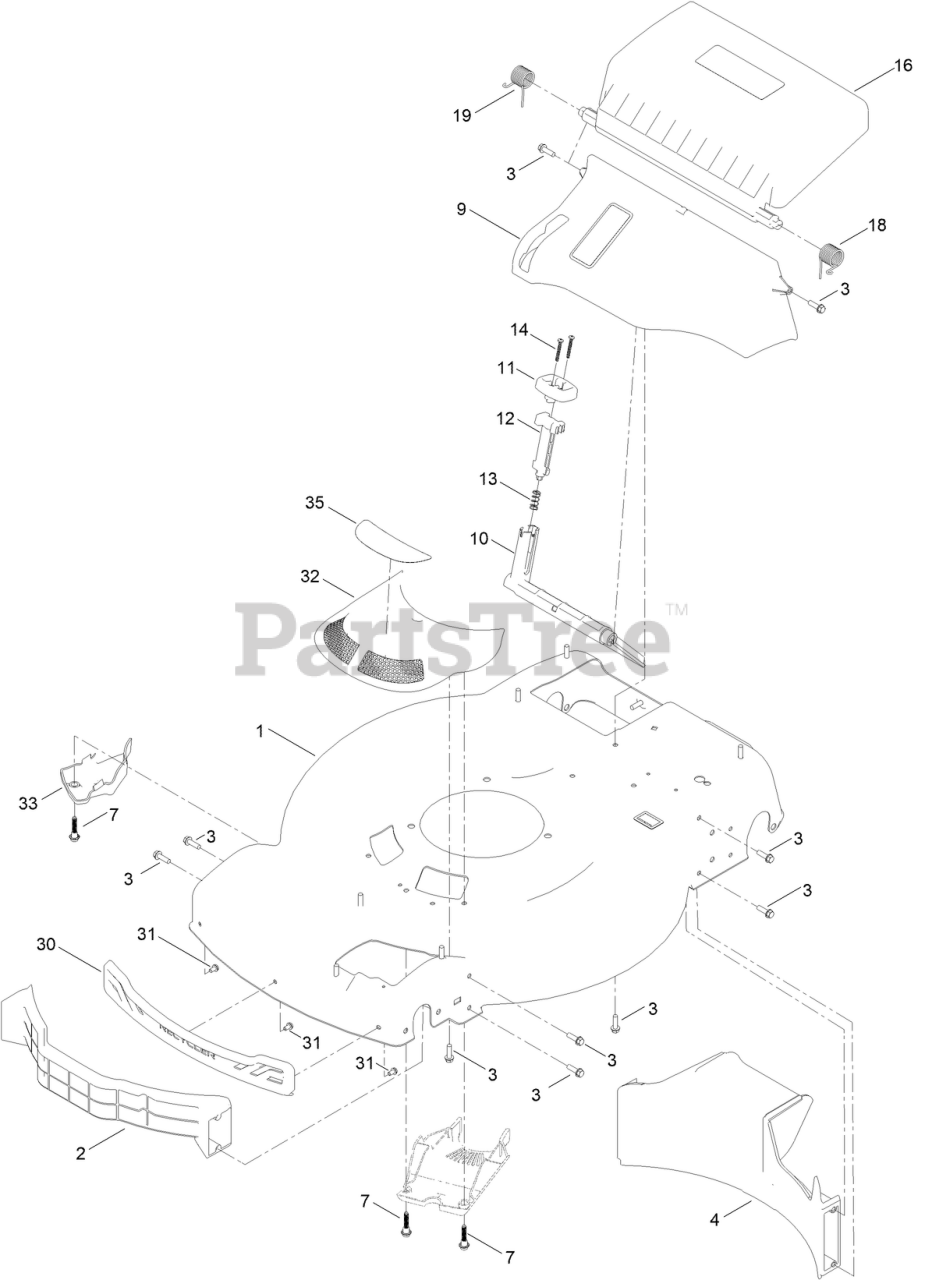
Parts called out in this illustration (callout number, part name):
1	HOUSING ASM
2	BAFFLE-FRONT, DOMESTIC
3	SCREW-HWH
4	BAFFLE-REAR, RWD
7	SCREW-SHOULDER, HHF
9	ASM-CHUTE, IN MOLD
10	DEFLECTOR-RECYCLE
11	KNOB-RECYCLE
12	LATCH-RECYCLE
13	SPRING-COMPRESSION
14	SCREW-PPH
16	ASM-REAR DOOR, IN MOLD
18	SPRING-TORSION, LH
19	SPRING-TORSION, RH
30	BUMPER-FRONT
31	SCREW-PLASTIC, HWH
32	ASM-INTAKE, RWD
33	COVER-INTAKE, BOTTOM
